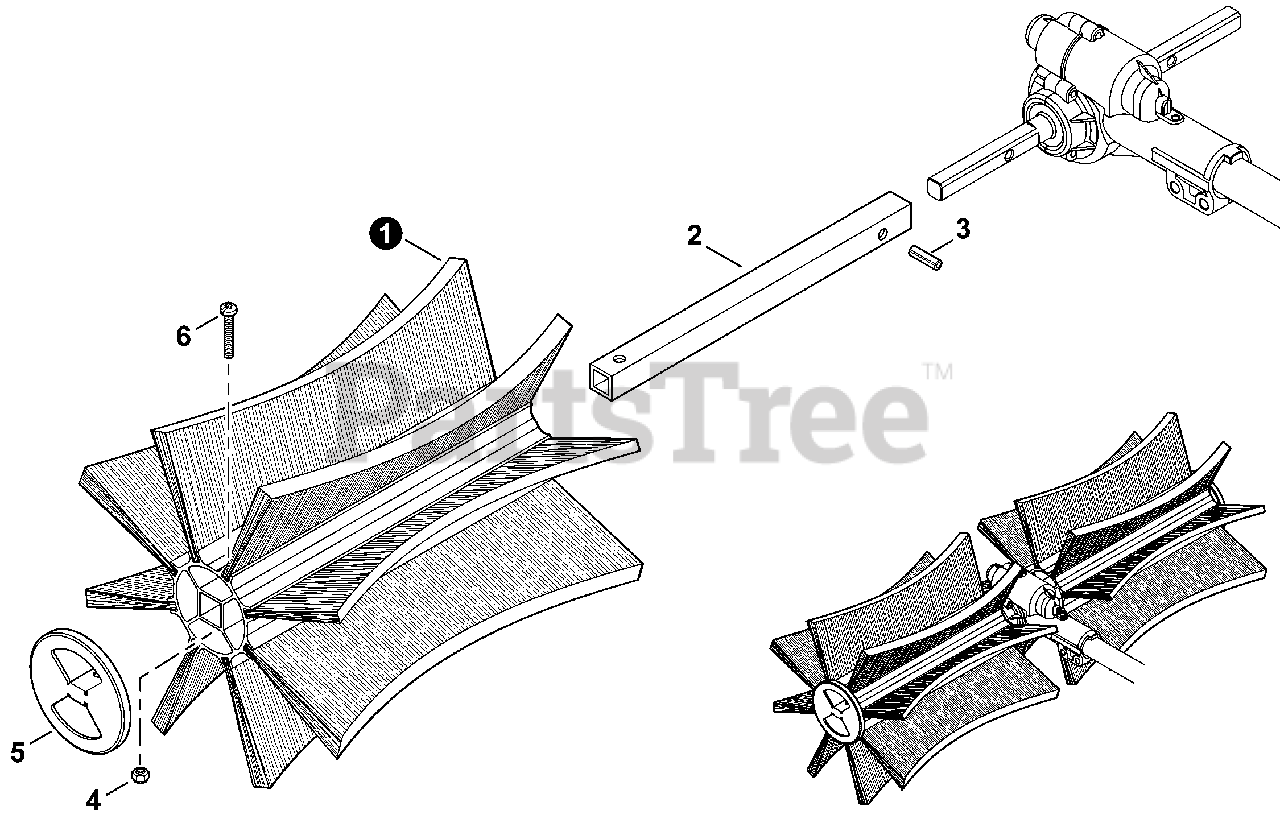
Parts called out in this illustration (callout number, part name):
1	BRUSH KIT (2 pieces)
2	SHAFT, DRUM
3	PIN, SPRING
4	NUT, LOCK M5
5	CAP, DRUM
6	SCREW 5×30
